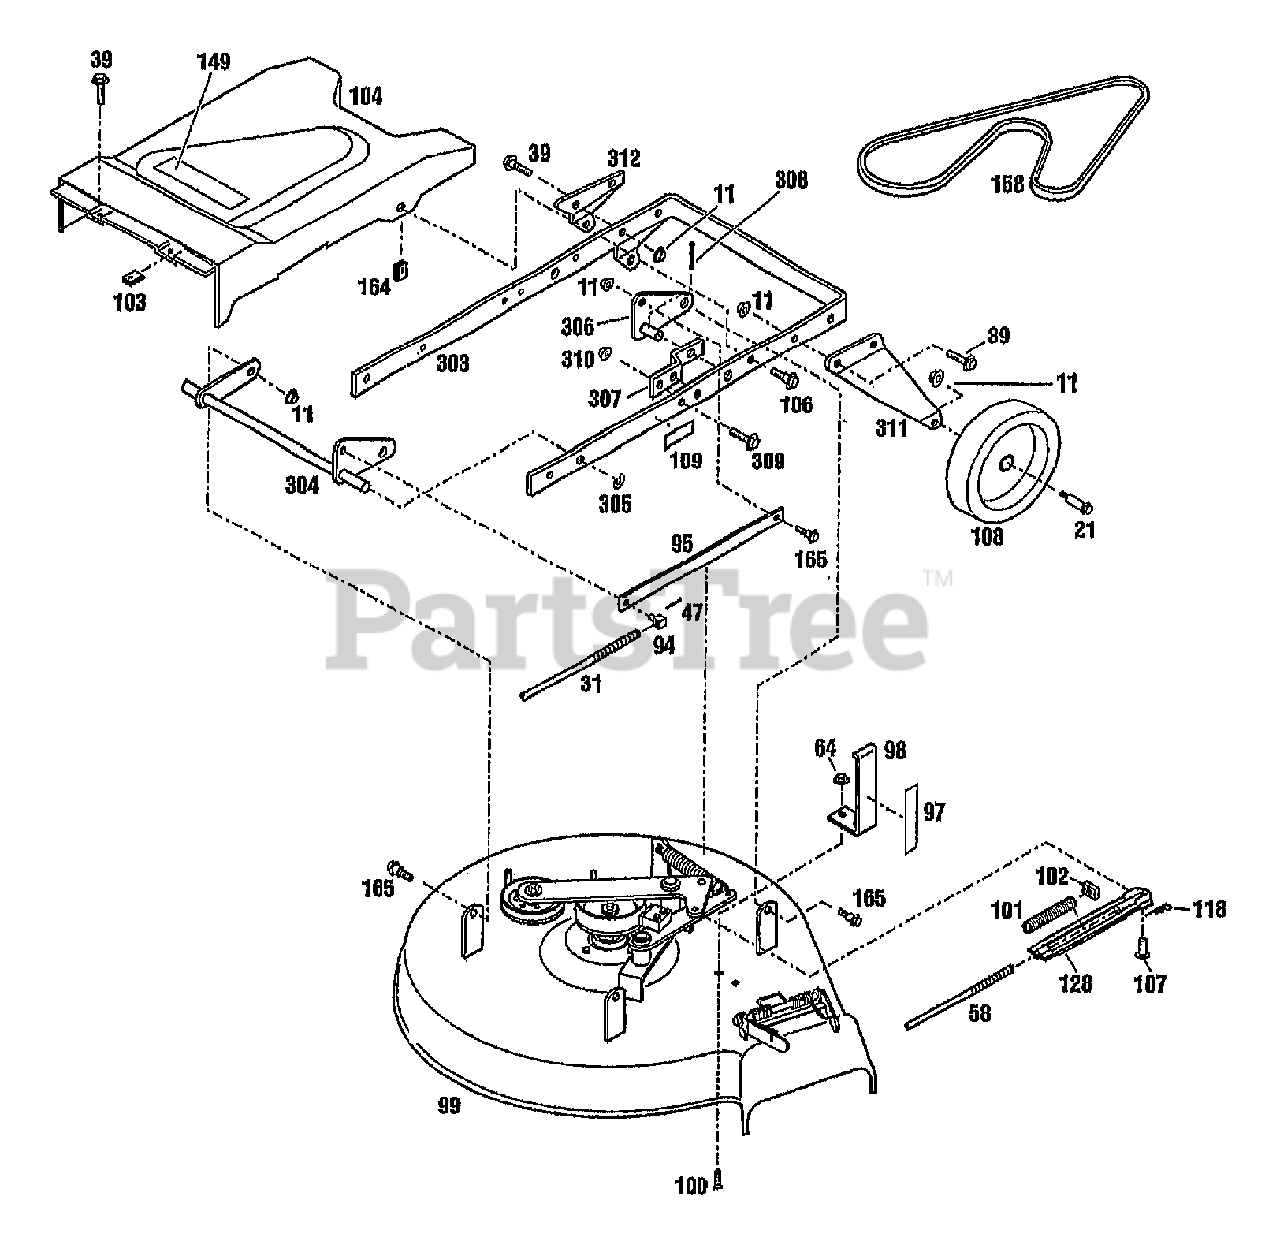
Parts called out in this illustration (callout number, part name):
11	NUT-HFLK 3/8-16
21	SCR-SHLDR 3/8-16
31	ASSM-CRANK LIFT
39	SCR-HFLK 3/8-16X1.00
47	PIN-COTTER .125 X .75
58	ROD-LOWER
64	NUT-HFLK 5/16-18
94	BLOCK-PIVOT
95	BAR-LEVELER
97	DECAL-CUTTING HEIGHT
98	BRKT-HT ADJ/DOWN
99	DECK ASSEMBLY (GRID A-9)
100	SCR-CARR 5/16-18X.75
101	SPRING
102	NUT-SPECIAL
103	CLIP-J TYPE
104	COVER-BELT
106	SCR-HFLK 1/4-20X.75 G5
107	PIN-CLEVIS .25X.62
108	ASSM-TIRE & WHEEL
109	DECAL-CUT LINE
118	PIN-CLIP .08
128	SPRING-YOKE ASSM
149	DECAL-LOGO TROY BILT
158	BELT-V
164	NUT-SPEED
165	SCR-SHLDR 3/8-16X.25 G5
303	FRAME-FRONT {34038,34039}
303	FRAME-FRONT {34037,34036}
305	RING-RETAINING
306	ARM-PIVOT
308	PIN-COTTER .125X1.5
309	SCR-LOCK
310	NUT-HFLK 5/16-18
311	SUPPORT-WHEEL (FFRH)
312	SUPPORT-WHEEL (FFLH)
